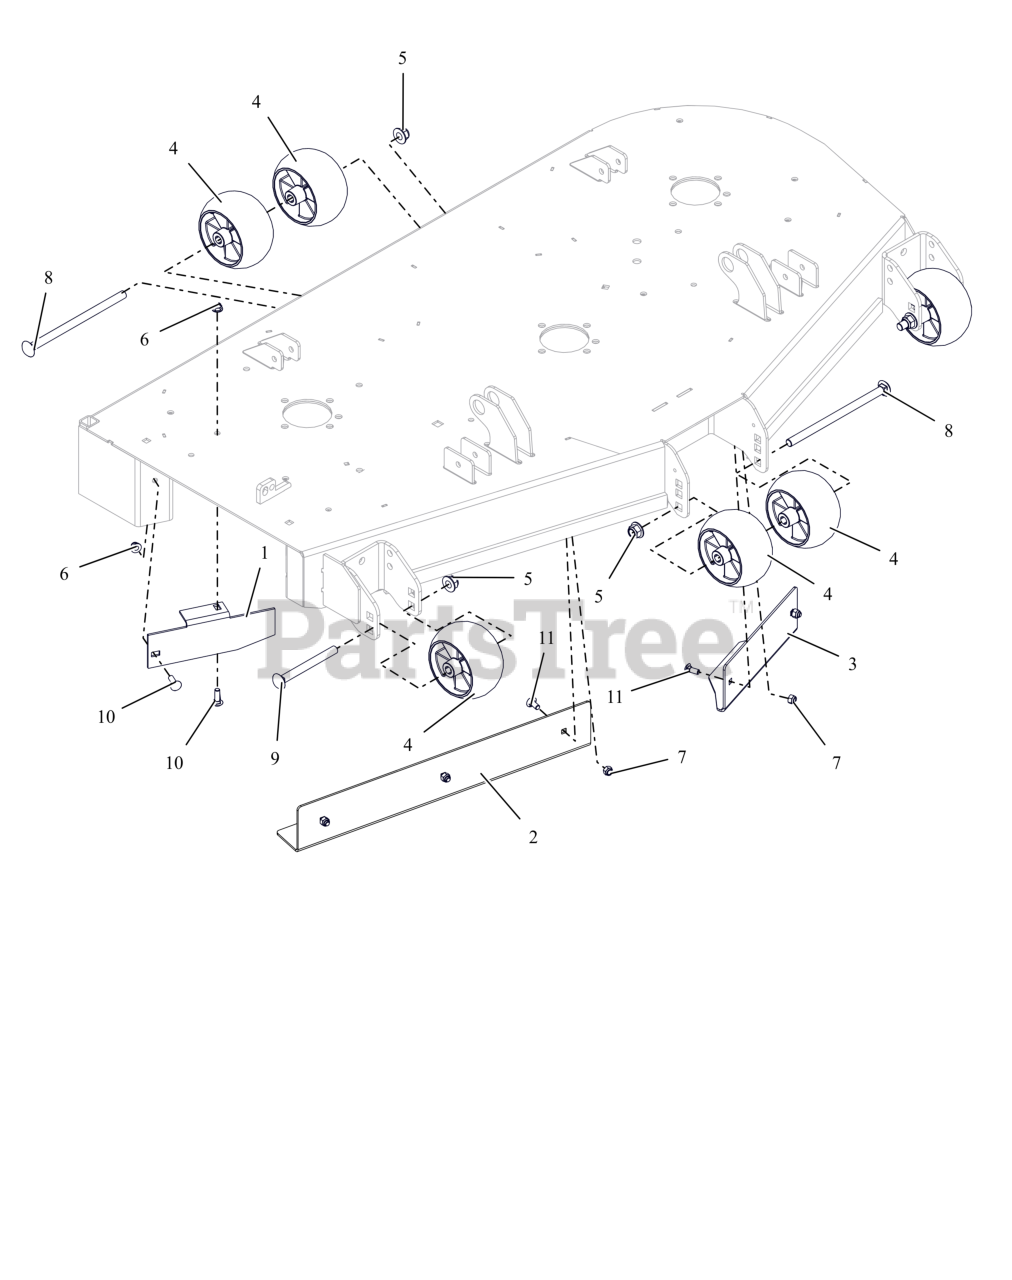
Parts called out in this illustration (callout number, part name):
1	BAFFLE, DISCHARGE, 52"
2	BAFFLE, 52" RH VACUUM (RED)
3	BAFFLE, 52" LH VACUUM (RED)
4	WHEEL, ANTI SCALP - 5X3 CTR W/RIBS
5	NUT,NYL-FLG .50-13 GF ZCC
6	NUT,NYL-FLG .31-18 GF ZCC
7	NUT,NYL .31-18 G5 ZCC
8	BTL,RHSN .500-13 X 8.5S G5 ZCC
9	BLT, RHSN .50-13X5.00 G5 ZCC
10	BLT,RHSN .31-18X1.00 G5 ZCC
11	BLT,RHSN .31-18X.75 G5 ZCC
